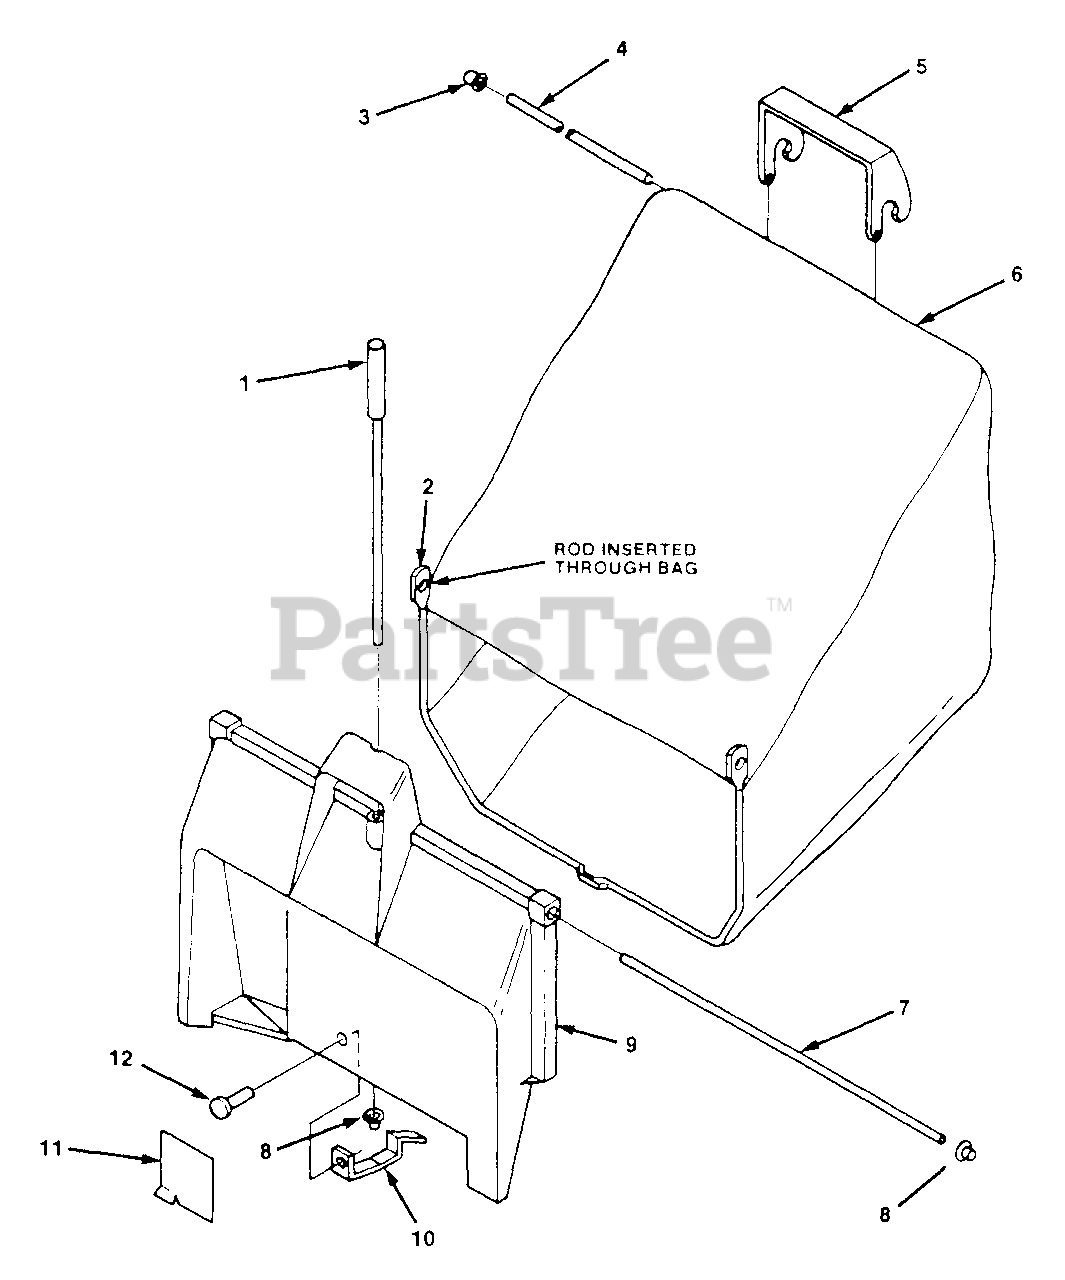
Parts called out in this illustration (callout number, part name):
1	ROD, LATCH RELEASE
2	ROD, BAG SUPPORT
3	END, ROD
4	ROD, UPPER BAG
5	HANDLE
6	BAG, GRASS
7	ROD, BAG HINGE
8	NUT, PAL
9	ADAPTER, BAG
10	LATCH
11	DEFLECTOR
12	RIVET
